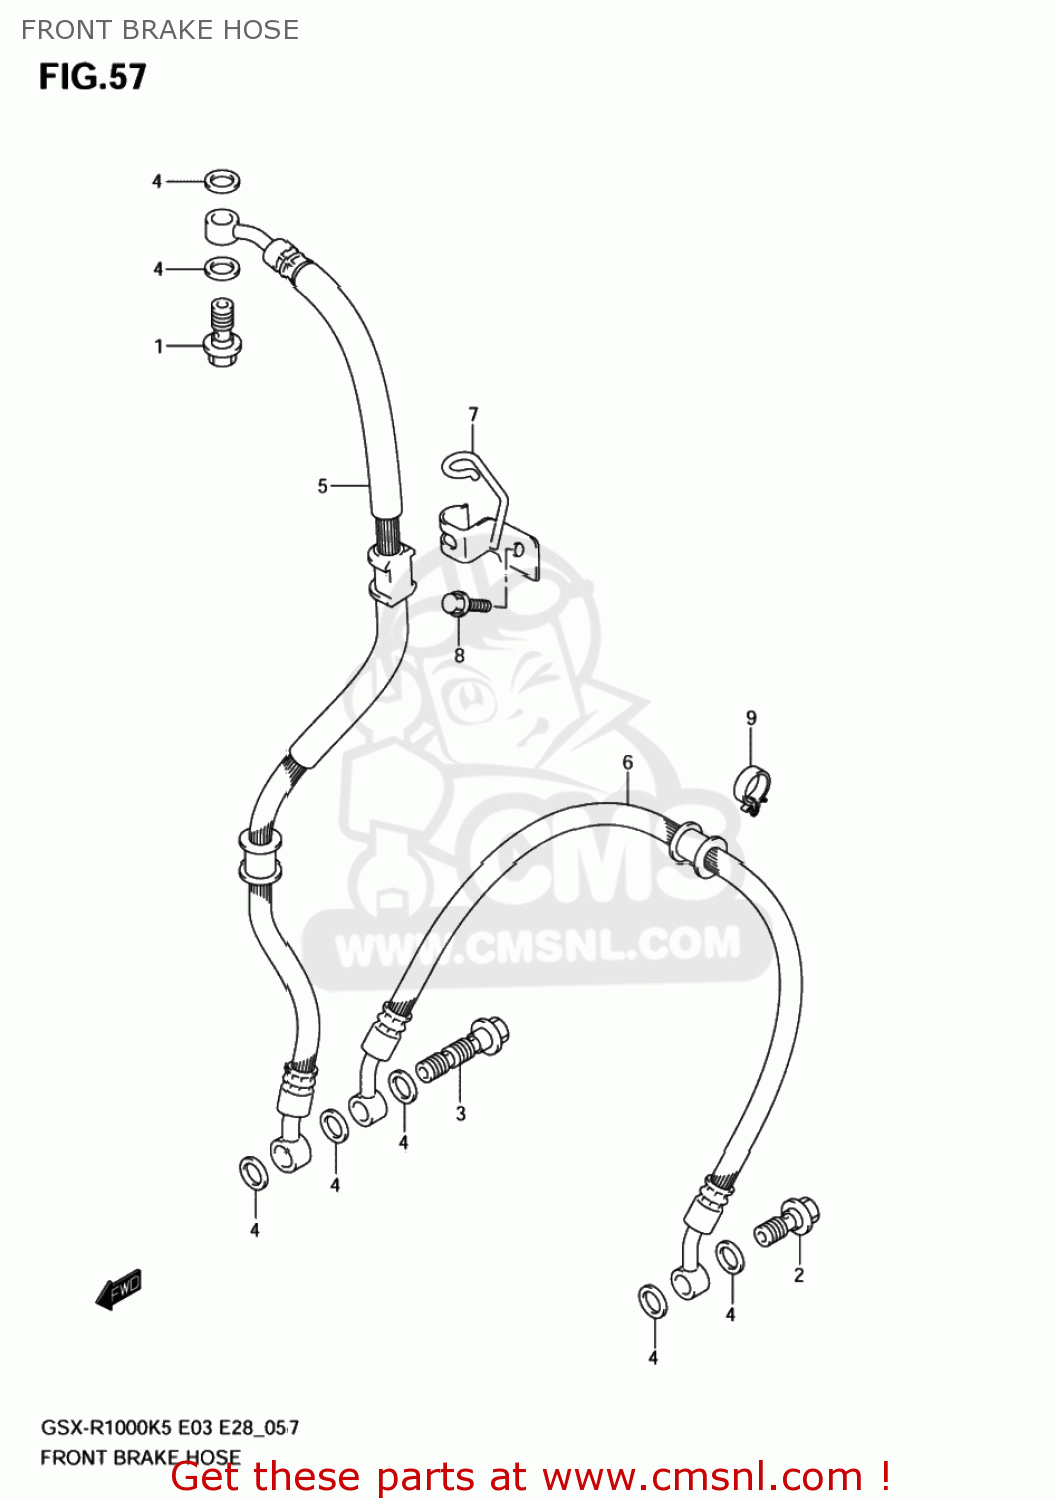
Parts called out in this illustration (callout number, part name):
1	BOLT UNION
2	BOLT UNION
3	BOLT UNION
4	WASHER(10X15X1.5)
5	HOSE COMP,FR B
6	HOSE, FRONT BRAKE NO.2
7	CLAMP,FR BRAKE HOSE NO.1
8	BOLT
9	CLAMP
